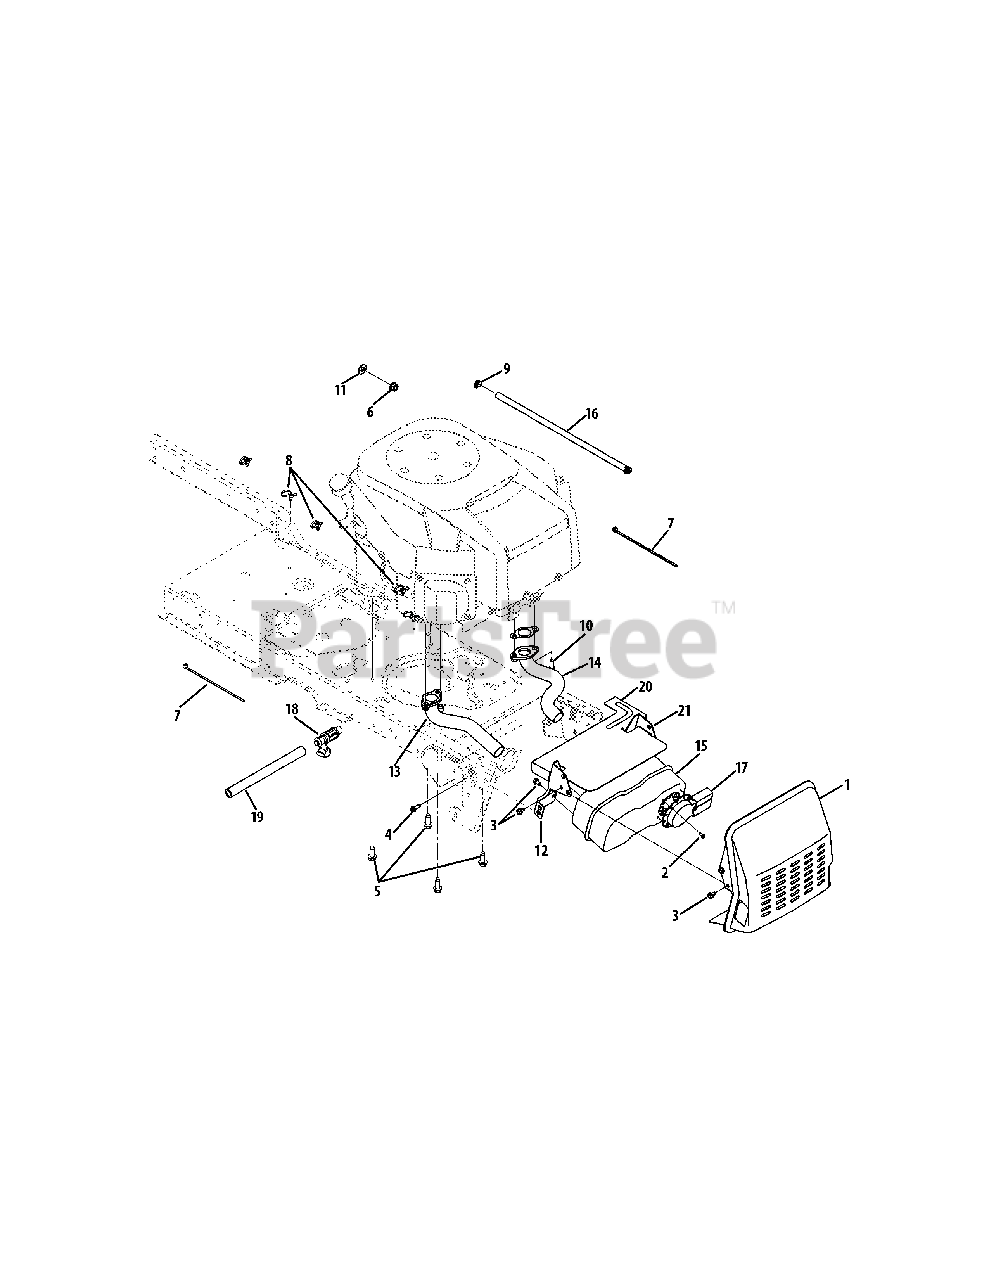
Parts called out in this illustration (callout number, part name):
1	Muffler Shield
2	Hex Washer Screw, #8-18 x .5
3	Hex Washer Screw, 1/4-20 x .5
4	TT Screw, 1/4-20 x .625
5	Hex Screw, 3/8-16 x 1.0
6	Hex Lock Nut, 3/8-16
7	Cable Tie
8	Fuel Line Cable Tie, 7.5
9	Hose Clamp
10	Hex Screw, 5/16-18 x .75
11	Flat Washer, .406 x .875 x .059
12	RH Muffler Bracket
13	RH Exhaust Pipe
14	LH Exhaust Pipe
15	Dual Inlet Muffler
17	Muffler Deflector
18	Oil Drain Valve
19	Oil Drain Extension Hose
20	Heat Shield
21	LH Muffler Bracket
